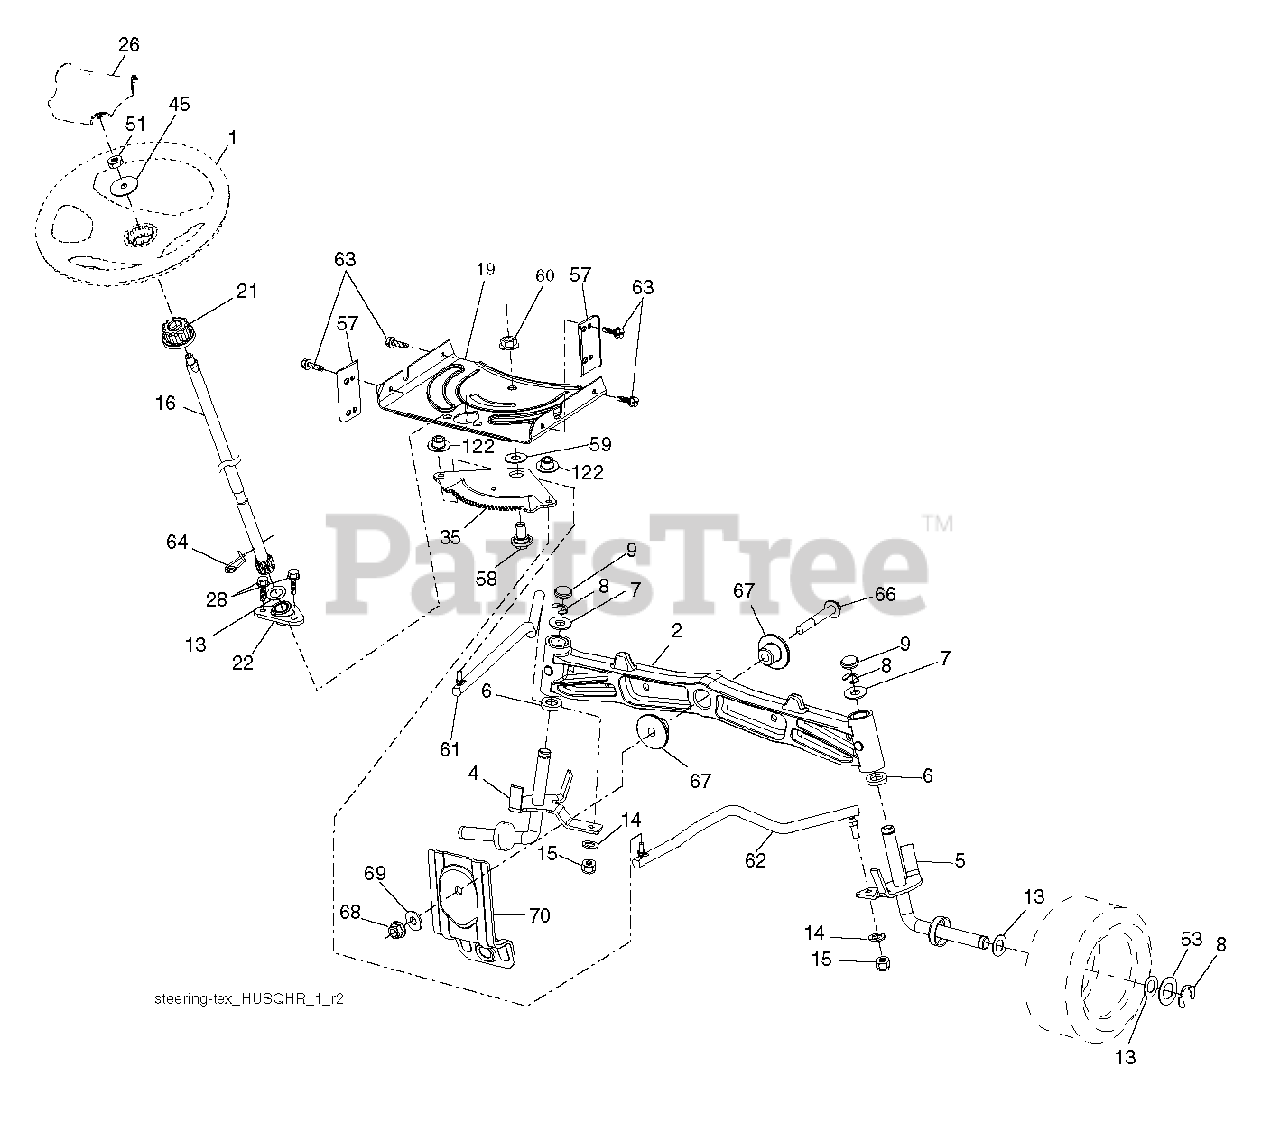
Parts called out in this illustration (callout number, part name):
1	WHEEL.STEER.HUSQ.SR.498.OVMLD
2	AXLE.CAST.IRON
4	SPINDLE.WELDED.LH.15"TEX
5	SPINDLE.WELDED.RH.15"T
6	THRUST WASHER
9	CAP.SPINDLE.BLACK
14	WASHER, LOCK 3/8
15	NUT CROWNLOCK 3/8-24
16	SHAFT, STEERING
19	PLATE.STEER.DDL.NLT/NG
21	ADAPTER, WHEEL STNG..
22	STEERING.SUPT.LOWER.
26	INSERT.CAP.WHL.STRG.HUSQ.PREM
28	SCREW, 3/8-16X3/4
35	GEAR.SECTOR.PLATE.DDL.
45	WASHER 9/16"ID, 2 3/8"OD
51	NUT.HEX.1/2-20
53	WASHER.HARDENED
57	BRACKET.UPSTOP.TEX
58	BOLT.SHOULDER.SECTOR.P
59	WASHER.THURST.SECTOR.S
60	NUT FLANGE LOCK 5/8-11
61	DRAGLINK.LH.BALLSTUD.D
62	DRAGLINK.RH.BALLSTUD.D
63	SCREW
64	RETAINER.CLIP.SPRING.S
66	BOLT HEX FGHD 7/16-14 X 3 SERR
67	BUSHING.PM.FRONT AXLE
68	NUT.LOCK.FLANGE.7/16
69	WASHER.1.5X.505X.118
70	BRKT.DECK.SUSPENSION.F
122	CAP.GEAR.SECTOR.TEX
